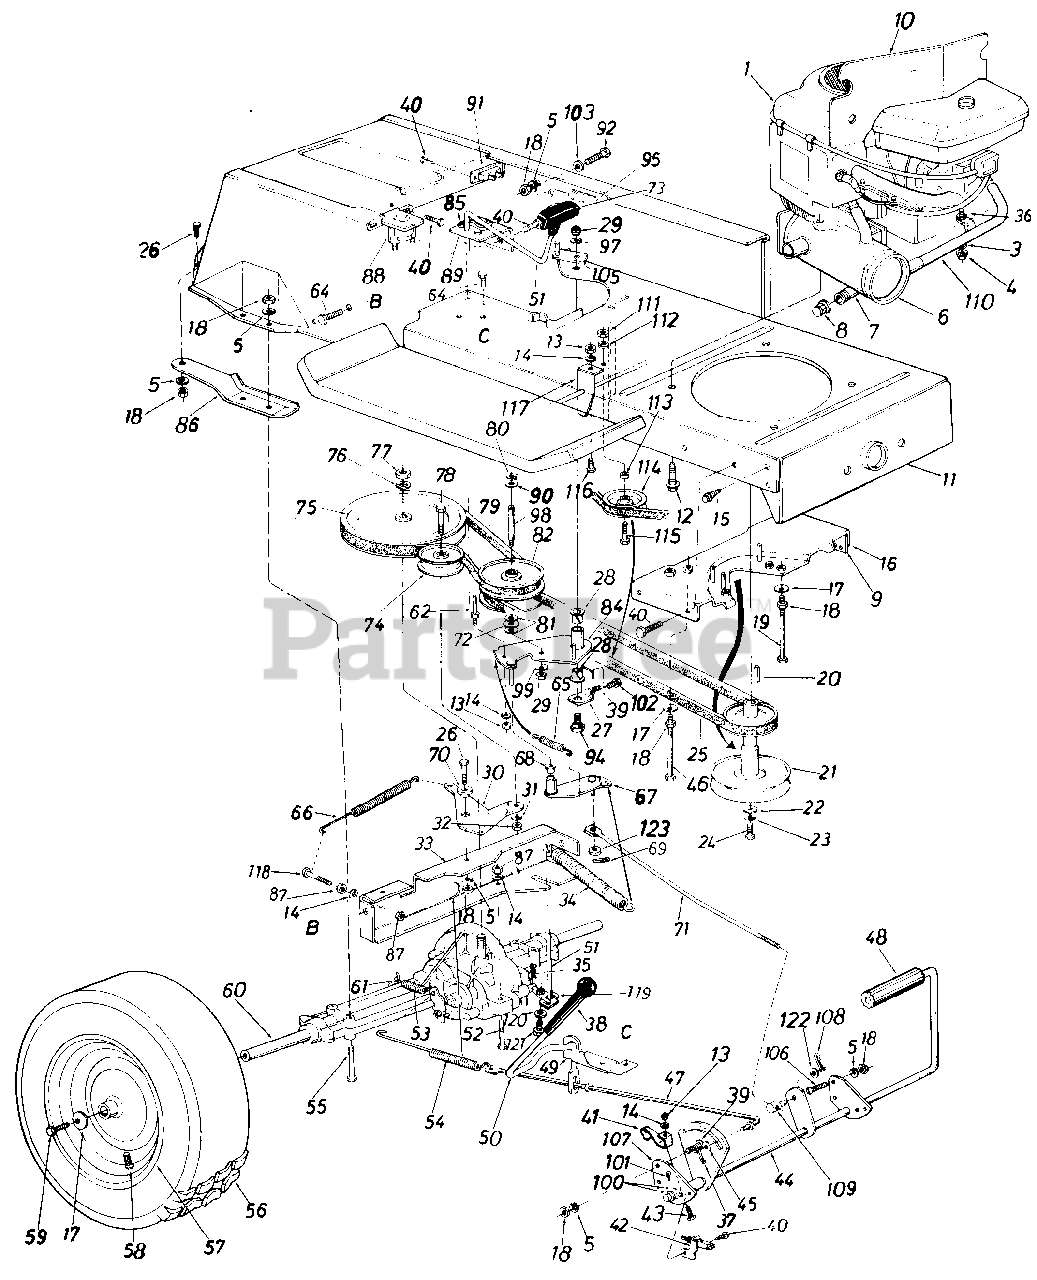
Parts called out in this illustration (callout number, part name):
1	Engine
3	Special L-Wash. 5/16" I.D.
4	Hex Nut 5/16-18 Thd.
5	L-Wash. 5/16" I.D.
6	Exhaust Muffler
7	Pipe Nipple
8	Cap Oil Drain
9	Brake Cable Brk't.
10	Heat Shield
11	Lower Frame Ass'y.
12	Hex Wash. Hd. TT-Tap Scr. 3/8-16 x 1.25" Lg.
13	Hex Nut 1/4-20 Thd.
14	L-Wash. 1/4" I.D.
15	Hex Wash. Hd. AB-Tap Scr. 5/16" x .75" Lg.
16	Belt Guard Brkt. Ass'y.
17	Bell-Wash. .345" I.D. x .88"
18	Hex Nut 5/16-18 Thd.
19	Hex Bolt 5/16-18 x 4.00"
20	Sq. Key 1/4" X 1/4" x 2.00"
21	Engine Pulley
22	Fl-Wash. 7/16" I.D. x 1.25"
23	L-Wash. 7/16" I.D.
24	Hex Bolt 7/16-20 x 1.50" Lg.
25	Variable-Speed Belt
26	Hex Bolt 5/16-18 x .75" Lg.
27	Bearing Shaft Bracket Ass'y.
28	Flanged Nyliner Brg. 5/8" I.D. x .88" Lg.
29	Hex Nut 3/8-24 Thd.
30	Idler Bracket
31	L-Wash. 3/8" I.D.
32	Hex Nut 3/8-24 Thd.
33	Transaxle Support Brkt.
34	Ext. Spring .94" O.D. x 6.7
35	Inter. Cotter Pin
36	Fl-Wash. .34" I.D. x .62" O.D. x .033
37	Cotter Pin 3/32" Dia. x .75"
38	Grip Black
39	Truss Mach. Scr. 5/16-18 x .75" Lg.
40	Hex Wash. Hd. Self-Tap Scr. 1/4-20 x .50" Lg.
41	Switch Actuator
42	Safety Switch
43	Hex Bolt 1/4-20 x 1.0" Lg.
44	Clutch & Brake Pedal Ass'y.
45	Fl-Wash.
46	Hex Bolt 5/16-18 x 4.5"
47	Brake Rod 20.9" Lg.
48	Foot Pad
49	Brake Lever Bracket
50	Hill Holder Brake Handle
51	Shift Lever Ass'y.
52	Hex Bolt 1/4-28 x 1.75" Lg.
53	Ext Spring .38 O.D. x 2.5"
54	Ext. Spring .59" O.D. x 7.08"
55	Hex Bolt 5/16-18 x 2.75"
58	Air Valve
59	Hex Bolt 5/16-24 x .75" Lg.
60	Transaxle Complete R.H.
61	Brake Return Spring Anchor
62	Belt Guard Pin 1/4-20 Thd.
64	Hex Wash. TT-Tap Scr. 5/16 x .62" Lg.
65	Ext. Spring
66	Ext. Spring .62" O.D. x 6.12"
67	Variable Speed Torque Brkt. Ass'y.
68	Flanged Bearing
69	Cotter Pin 3132" Dia.
70	Shoulder Spacer .500" Dia. x .27" Lg.
71	Speed Control Link
72	Truss Bearing .56 Dia. x 1 .25"
73	Ball Knob
74	Fl-Idler Pulley 3.25" x 75"
75	1/2" "V"-Pulley 8.0" O.D. x .501" I.D.
76	L-Wash. 1/2" I.D.
77	Hex Jam Nut 1/2-20 Thd.
78	Hex Bolt 3/8-24 x .75" Lg.
79	Variable Speed Belt
80	Snap Ring .56" Dia.
81	Fl-Wash.
82	Variable Speed Pulley Ass'y. 5" O.D.
84	Variable Speed Brkt. Ass'y.
85	Comp. Spring Clip
86	Transaxle Support Brkt. R.H.
87	Hex Nut l/4-28 Thd.
88	Solenoid
89	Shift Lever Bracket
90	Teflon Washer
91	Circuit Breaker
92	Hex Bolt 5/16-18 x 1.50"
94	Shld. Bolt 3/8-24 x 3.12" Lg.
95	Ext. Spring .99" O.D. x 11.0"
97	Bell-Wash. .38" I.D. x .88"
98	Shaft .56" Dia. x 3.875" Lg.
99	Bell-Wash. .39" I.D. x 1.12"
100	Fl-Wash.
101	Cotter Pin 3132" Dia. x 75"
102	Hex Wash. Hd. Scr. 5/16-18 x.62" Lg.
103	Fl-Wash. .34" I.D. x 1.12" O.D.
105	Belt Guard
106	Hex Bolt 5/16-18 x .75" Lg.
107	Pedal Bracket
108	Cotter Pin 3/32 x .75
109	Ferrule
110	Inlet Tube Ass'y.
111	Hex Nut 3/8"-16 Thd.
112	L-Wash. 3/8" I.D.
113	Fl-Wash. .390" I.D. x 1.12"
114	Fl-Idler w/Flanges 2.750
115	Hex Bolt 3/8-16 x 2.00" Lg.
116	Hex Bolt 1/4-20 x .62" Lg.
117	Spring Hanger Bracket
118	Hex Bolt 1/4-28 x 1.25" Lg.
119	Shift Lever Link Ass'y.
120	Bell-Wash. .265 I.D. x .75 O.D.
121	Hex Bolt 1/4-28 x .62" Lg.
122	Fl-Wash. .385" I.D. x .62" C: .D.
123	Fl-Wash. .34" I.D. x .68" O.D.
